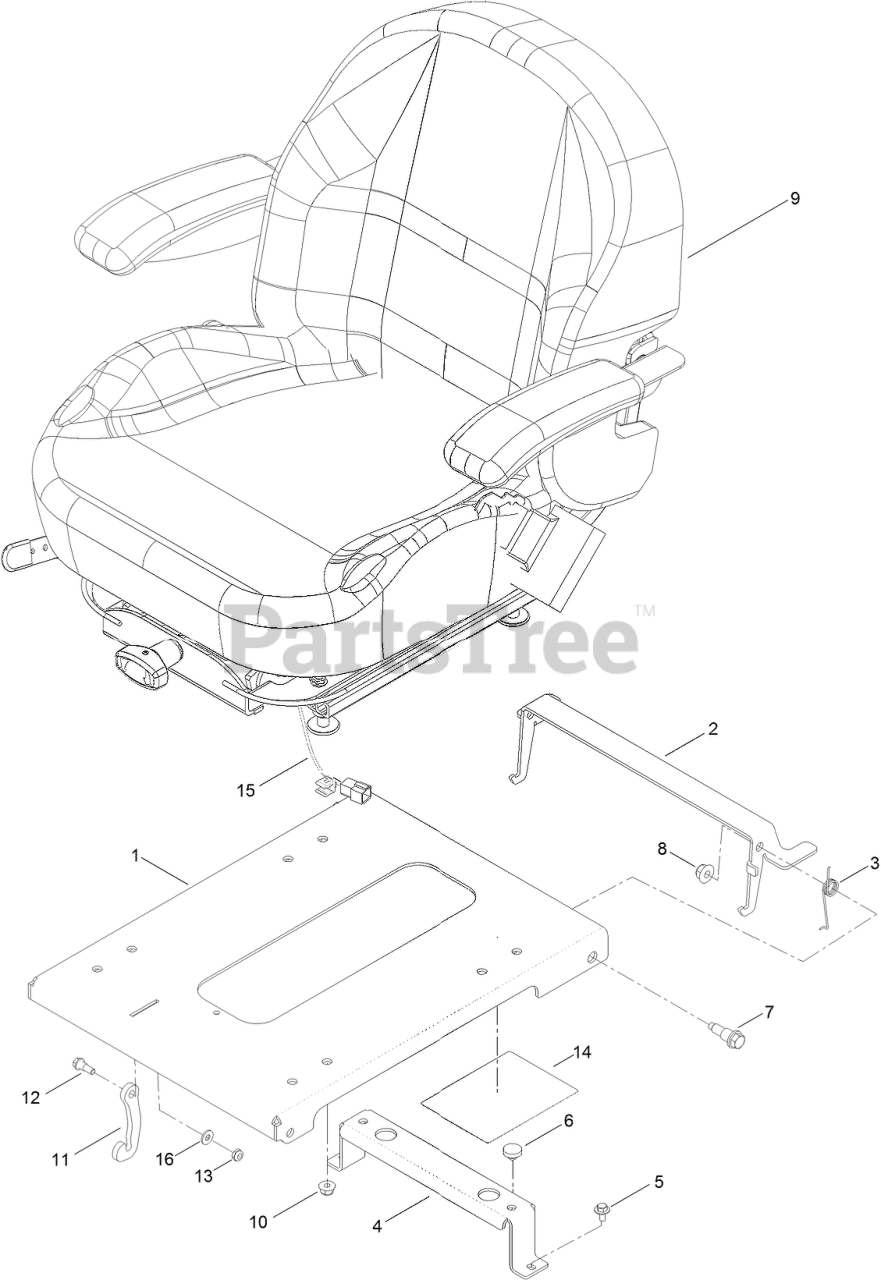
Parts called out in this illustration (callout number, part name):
1	SEAT PAN ASM
2	LATCH-SEAT
3	TORSION-SPRING
4	SEAT-SUPPORT, REAR
5	SCREW-HHFTF
6	BUMPER
7	BOLT-SHOULDER
8	NUT-HF, NI
9	SEAT-SUSPENSION
10	NUT-HF, NI
11	STOP-SEAT
12	BOLT-SHOULDER
13	NUT-LOCK, NI
14	DECAL-MAINTENANCE
15	HARNESS-WIRE
16	WASHER
